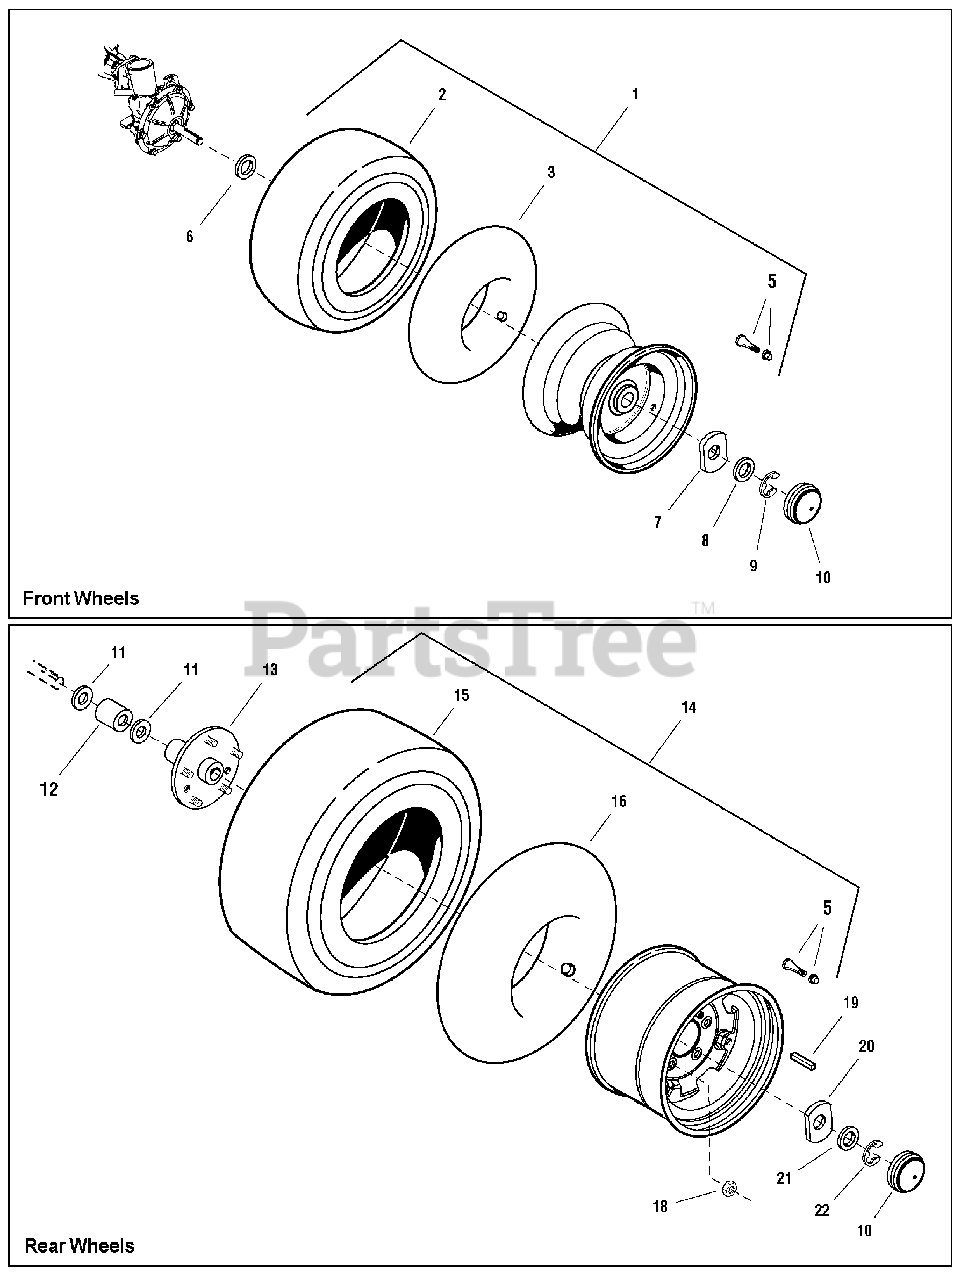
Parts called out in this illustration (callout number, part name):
1	WHEEL & TIRE ASSEMBLY
2	TIRE, 16 x 6-1/2-8
3	TUBE, Tire
5	VALVE STEM & CAP
6	WASHER, Flat, 3/4 x 1-5/8 x 1/8
7	WASHER, Flat
8	WASHER, 3/4
9	RING
10	CAP, Hub
11	WASHER, 1 x 2-1/4 x 1/8
12	SPACER
13	PLATE & HUB
14	WHEEL & TIRE ASSEMBLY
15	TIRE, 22 x 11-10
16	TUBE, Tire
18	NUT, Hex, 7/16-20
19	KEY, Hi-Pro, 1/4 x 2
20	WASHER, Flat
21	WASHER, Flat
22	RING
